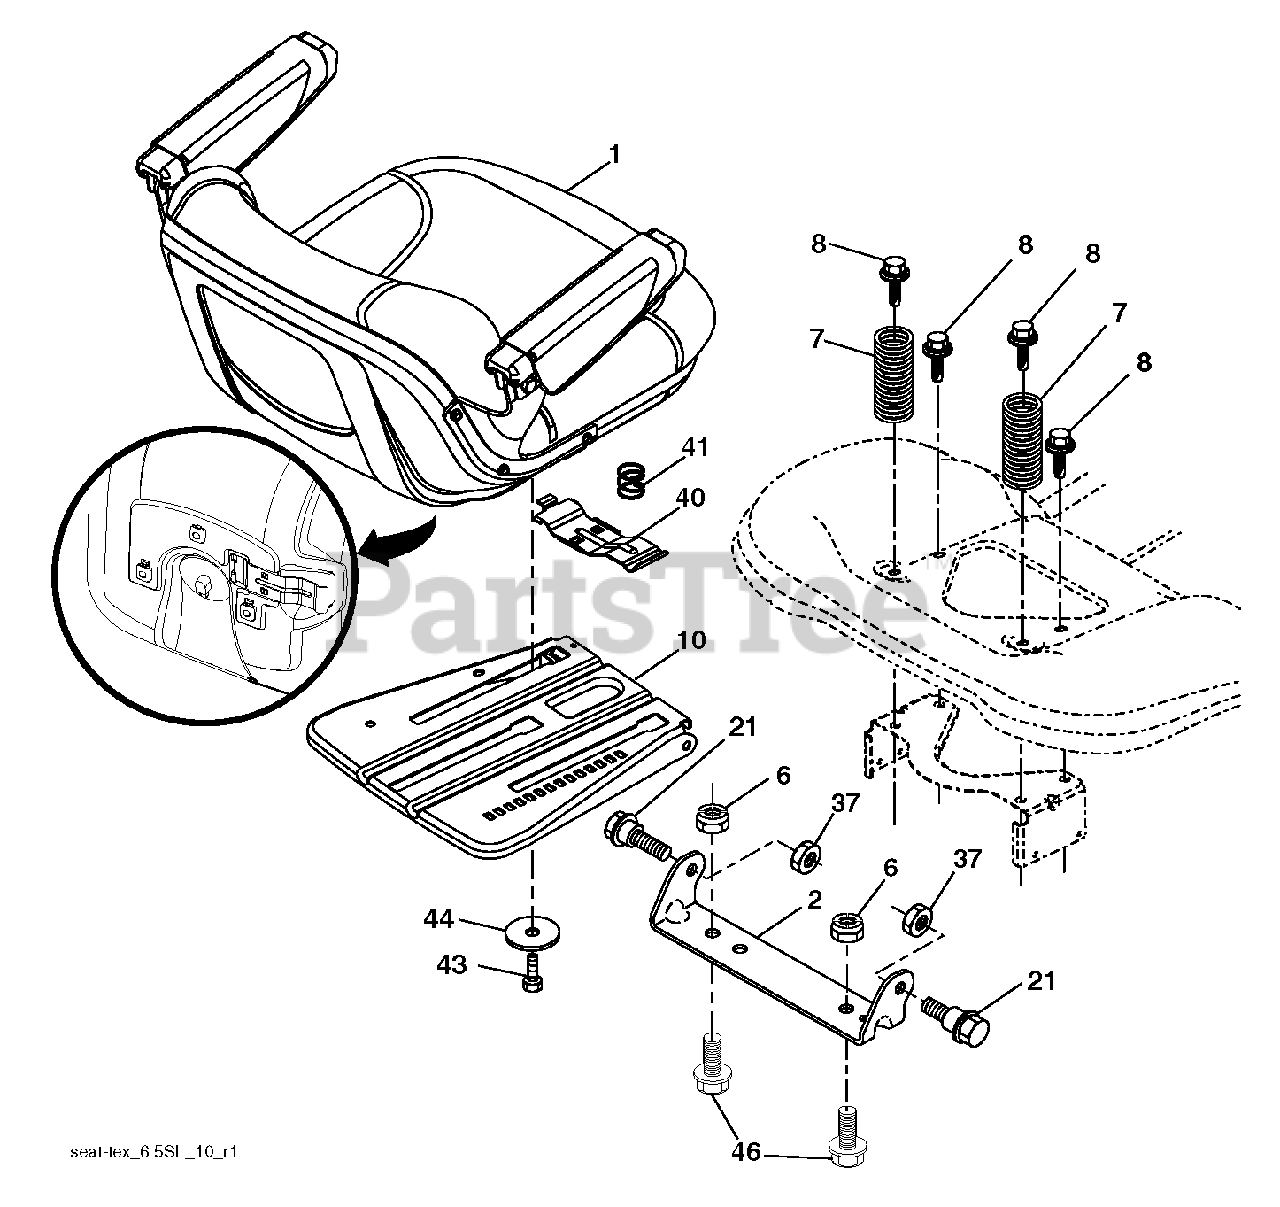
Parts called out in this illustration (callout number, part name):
1	SEAT TP153.TEX.ARMREST PPRO
2	BRKT.PIVOT.FENDER
6	NUT
7	Compression Spring, Seat Black
8	BOLT, 5/16-18 X 1 3/4
10	PAN.ASM.SEAT.3PT
21	Shoulder Bolt, 5/16-18 X 5/8
37	NUT.71038.31-18.HEX.NYLOCK
40	HANDLE.SLIDE.SEAT.TEX.BLACK
41	SPRING.LATCH.SEAT.TEX
44	WASHER 13/32 X 2-3/8 X 12GA
46	BOLT.3/8-16X1;1.25OD.WSHR.SEMS
